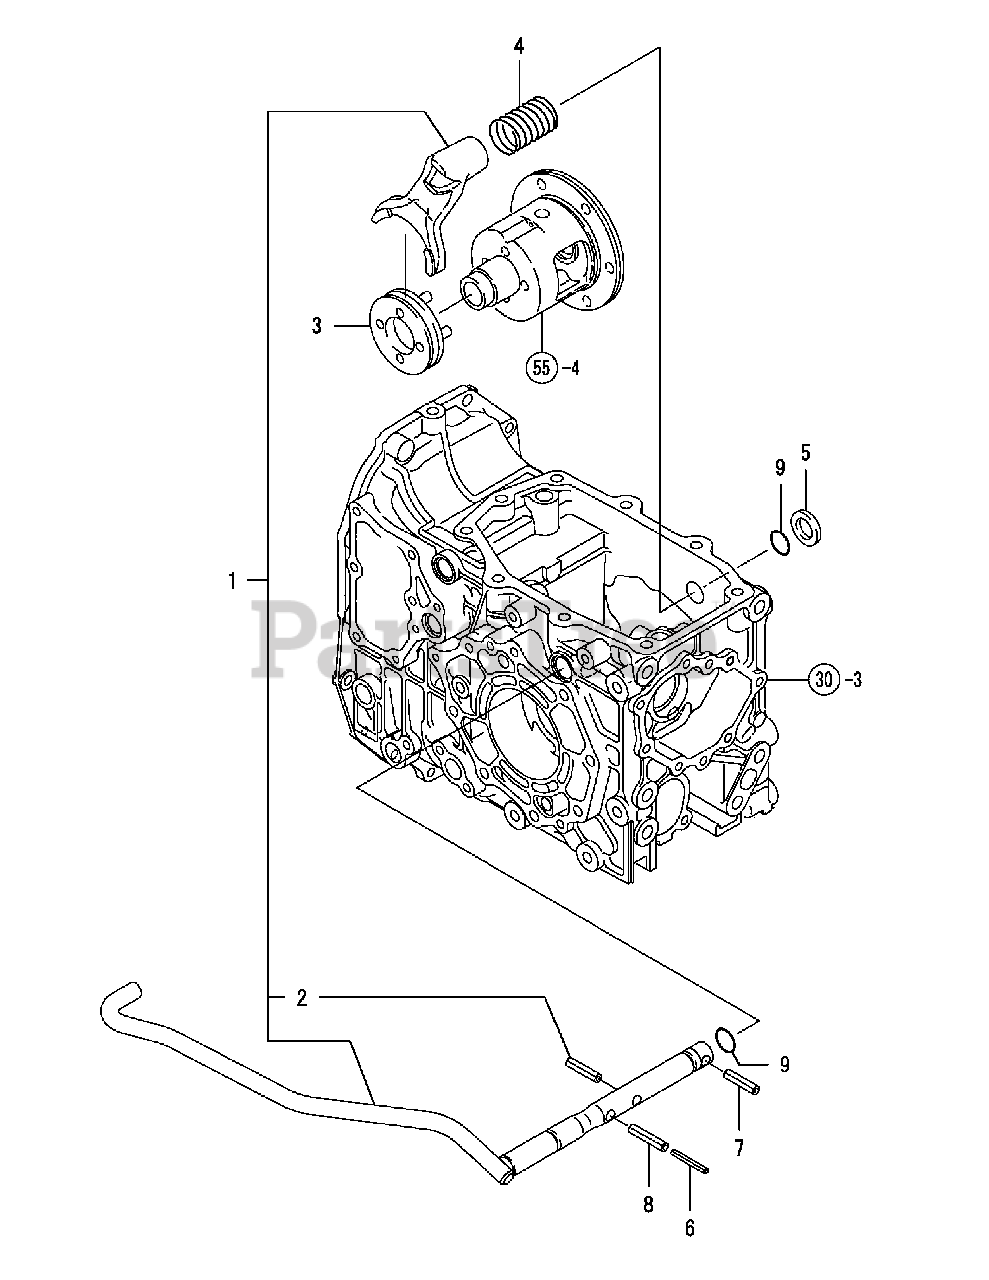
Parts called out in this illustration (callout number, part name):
2	Spring Pin 8X32
3	Slider, Diff.Lock
4	Spring, Diff.Lock
5	Spacer 20X25X3.2
6	Spring Pin 5X40
7	Spring Pin 8X32
8	Spring Pin 8X40
9	O-Ring 1A P-16.0
